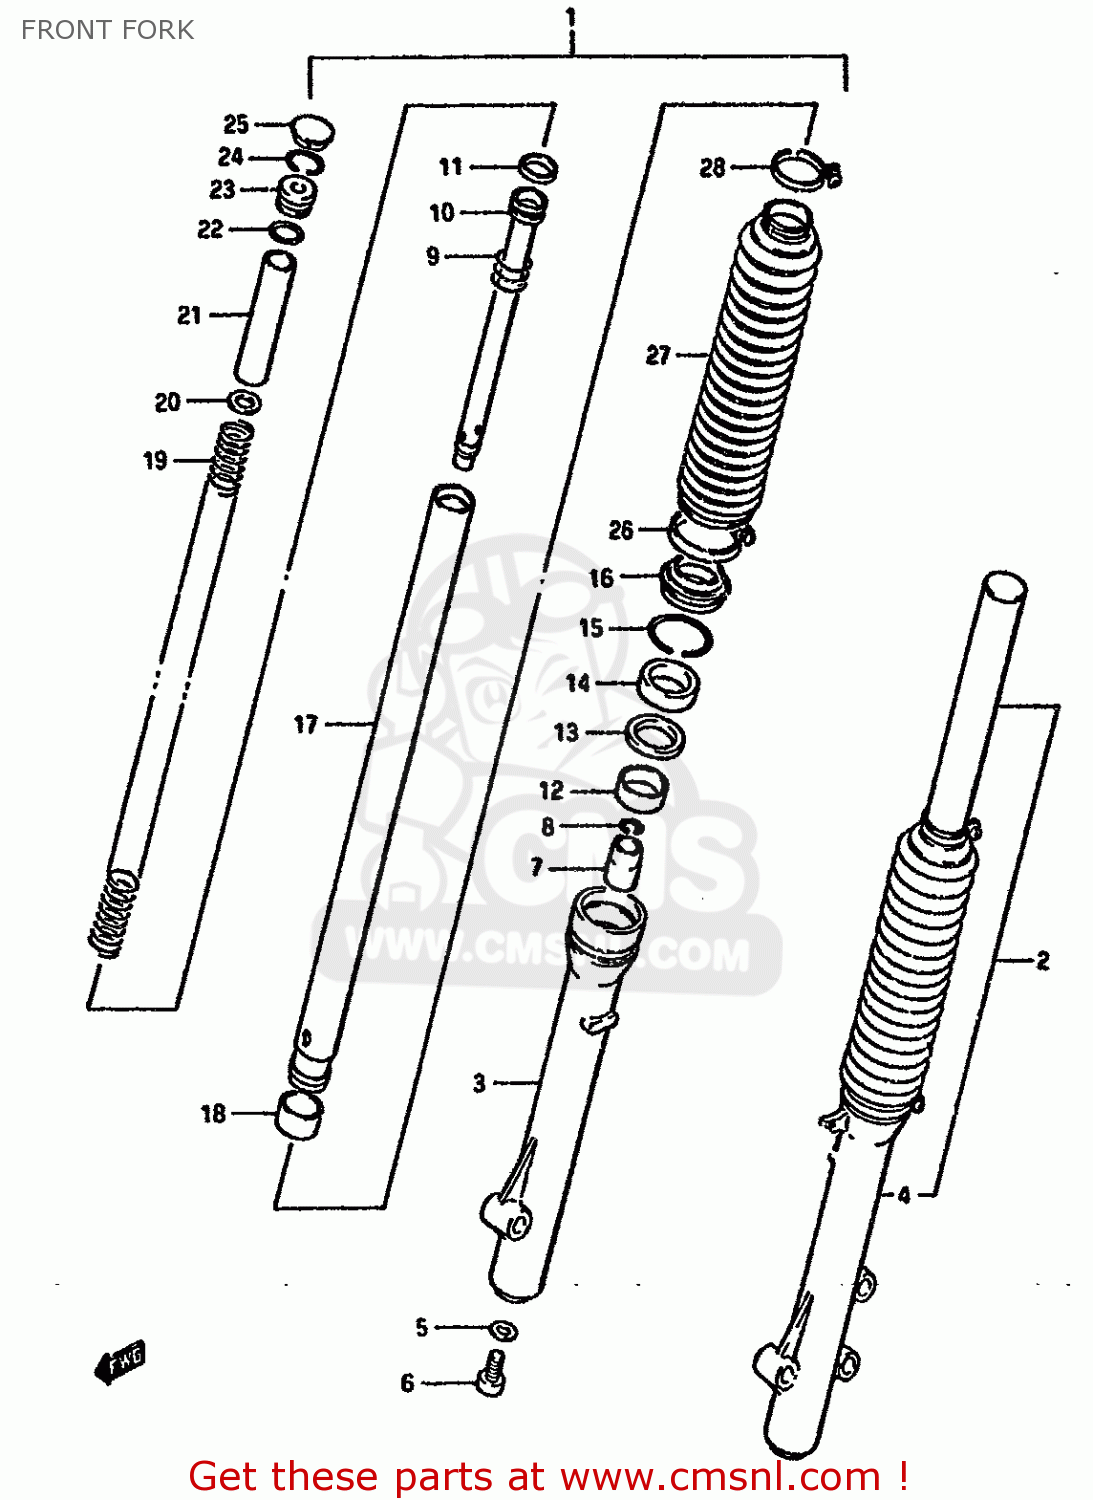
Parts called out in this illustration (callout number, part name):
1	DAMPER ASSY,FR FORK,R
2	DAMPER ASSEMBLY,LEFT
3	TUBE,OUTER,R
4	TUBE,OUTER,L
5	GASKET (NAS)
6	BOLT(8X27)
7	PIECE,OIL LOCK
8	RING,STOPPER
9	SPRING,REBOUND
10	CYLINDER,FRONT FORK
11	RING,PISTON
12	BUSH,GUIDE
13	SPACER,SEAL
14	OIL SEAL,FRONT FORK
15	CIRCLIP,FORK OIL SEAL
16	SEAL,DUST
17	TUBE,INNER
18	PISTON
19	SPRING
20	SPRING,JOINT
21	SPACER
22	O RING
23	SPRING SEAT B
24	RING,STOPPER
25	CAP
26	BAND
27	BOOT
28	BAND
